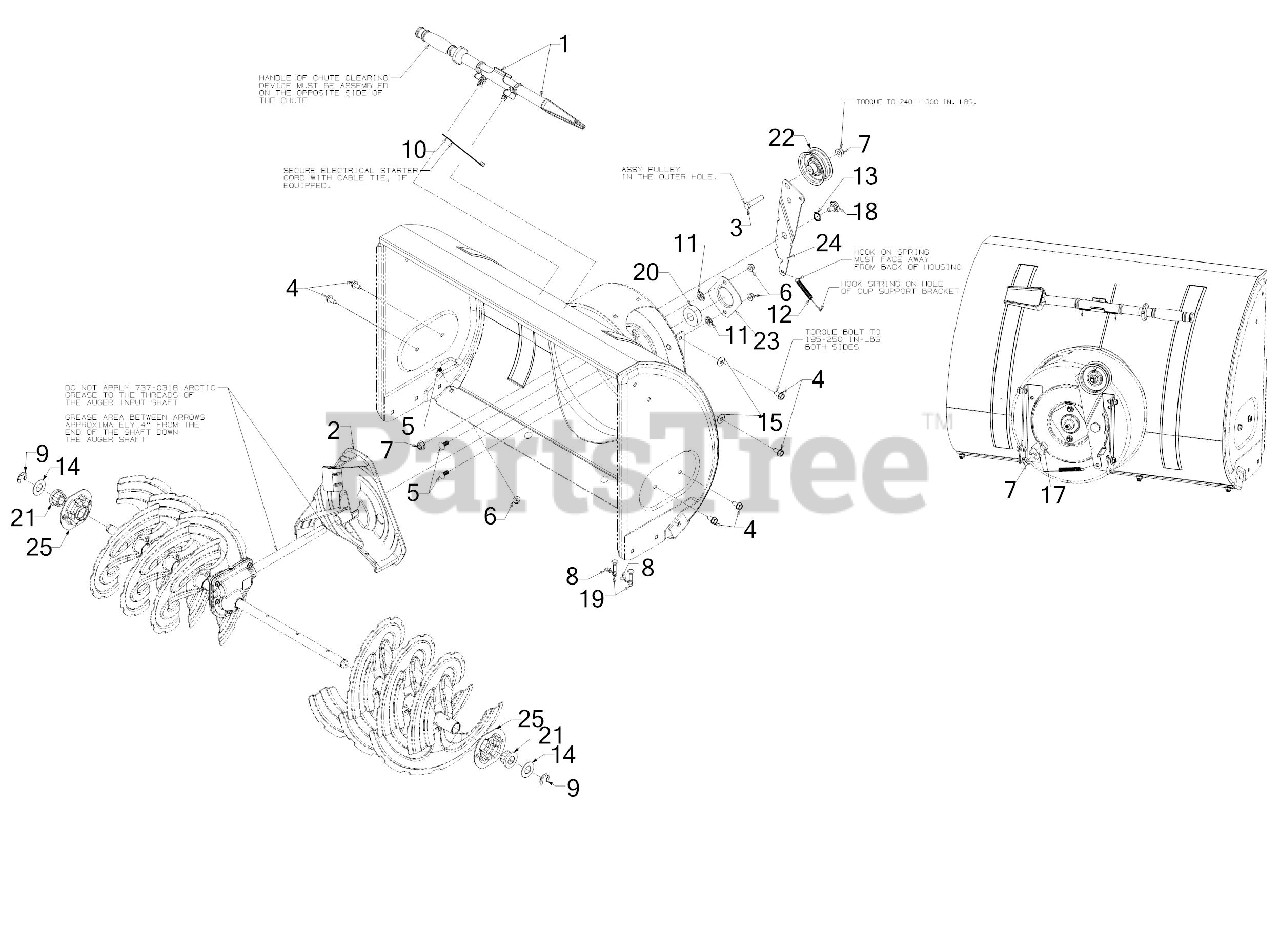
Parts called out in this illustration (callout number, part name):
1	CLEANOUT TOOL
2	3 BLADE 12" IMPELLER
3	HEX SCREW 3/8-16 x 1.75 GR5
4	SCREW 5/16-18 x .750
5	CARRIAGE BOLT 5/16-18 x .75
6	FLANGE LOCK NUT 5/16-18
8	BOW TIE COTTER PIN 1/4-5/16
9	E-RING
10	7" CABLE TIE
11	PUSH ON NUT
12	EXTENSION SPRING .38 OD x 4.59
13	WAVE WASHER .660 ID X.88 OD x .010
14	FLAT WASHER .760ID X1.49OD x .06
15	BELL WASHER .337 X.867 x .057
17	SHOULDER SCREW .498 DIA x .340
18	SHOULDER SCREW .625
19	SHEAR PIN .25 x 1.50 GR2
20	FLANGE BEARING
21	FLANGE BEARING
22	FLAT IDLER PULLEY 2.75 OD
23	BEARING HOUSIN 1.85 ID
24	AUGER IDLER BRACKET
25	HEX BREARING HOUSING
